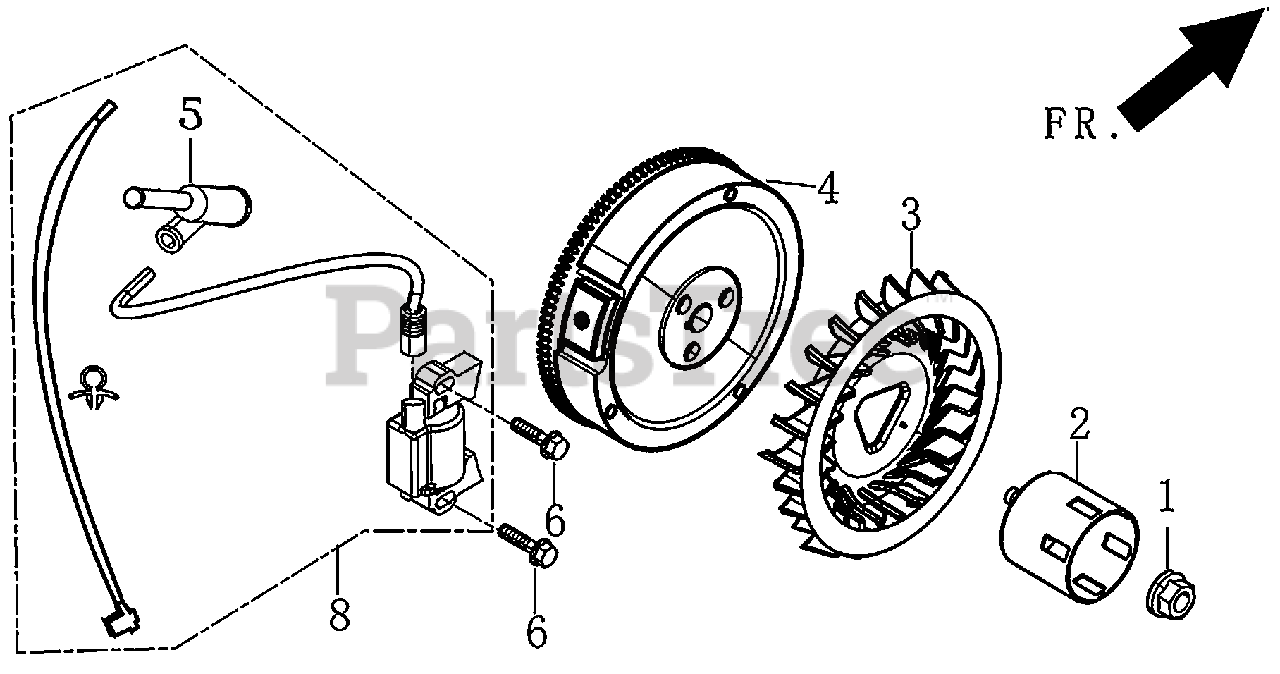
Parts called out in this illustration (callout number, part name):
1	NUT, FLYWHEEL
2	PULLEY,STARTER
3	FAN, COOLING
4	FLYWHEEL SUBASSEMBLY
5	Boot, Spark Plug
8	COIL, IGNITION
